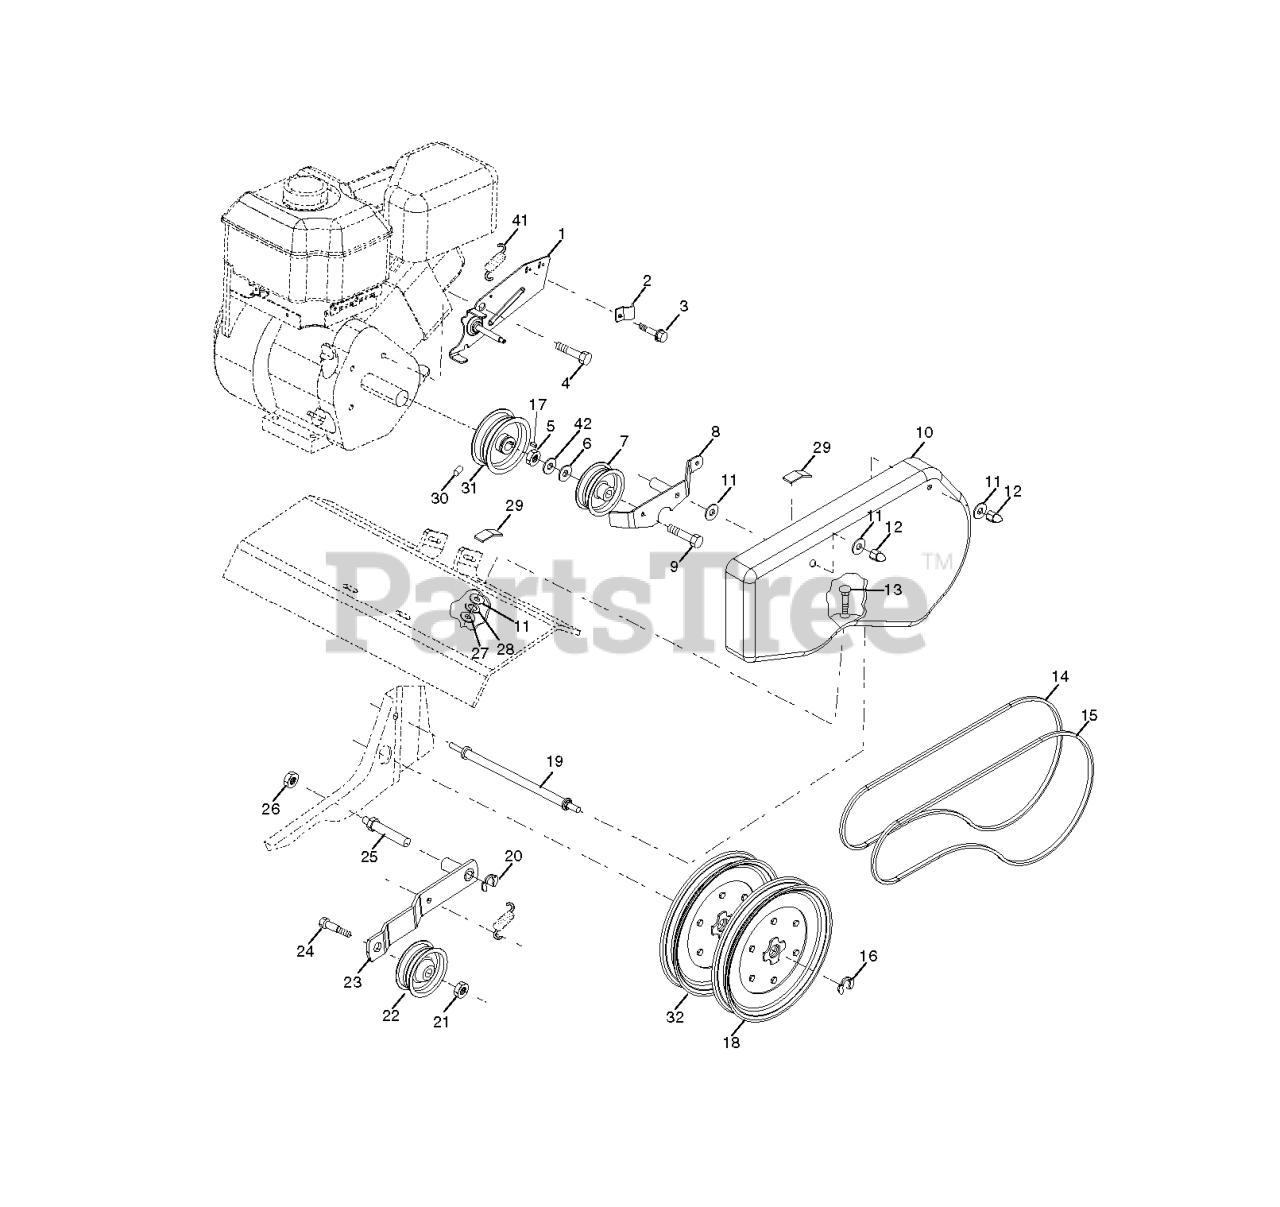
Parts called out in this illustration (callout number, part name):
1	BRACKET,BELTGUARD ASM
2	CONDUIT.CLIP.PLATED
3	TAPPING SCREW
6	WASHER
7	RP PULLEY.IDLER.2.44.TILLER
8	ARM
9	BOLT
10	GUARD.BELT.TILLER.ORANGE
12	CAP
13	BOLT
15	BELT.TILLER.DRIVE
16	RETAINING RING LT
18	SHEAVE,TRANS."D"
19	BOLT.BELT.GUARD
20	KLIP RING TI
21	NUT
22	PULLEY, IDLER
23	ARM.ASM.IDLER.BLACK
25	SHAFT.IDLER.TILLER
26	JAM NUT TI
27	NUT
28	LOCKWASHER
29	PAD IDLER TI
31	ENGINE.PULLEY.TILLER
32	SHEAVE.TRANS
41	SPRING.EXTENSION
